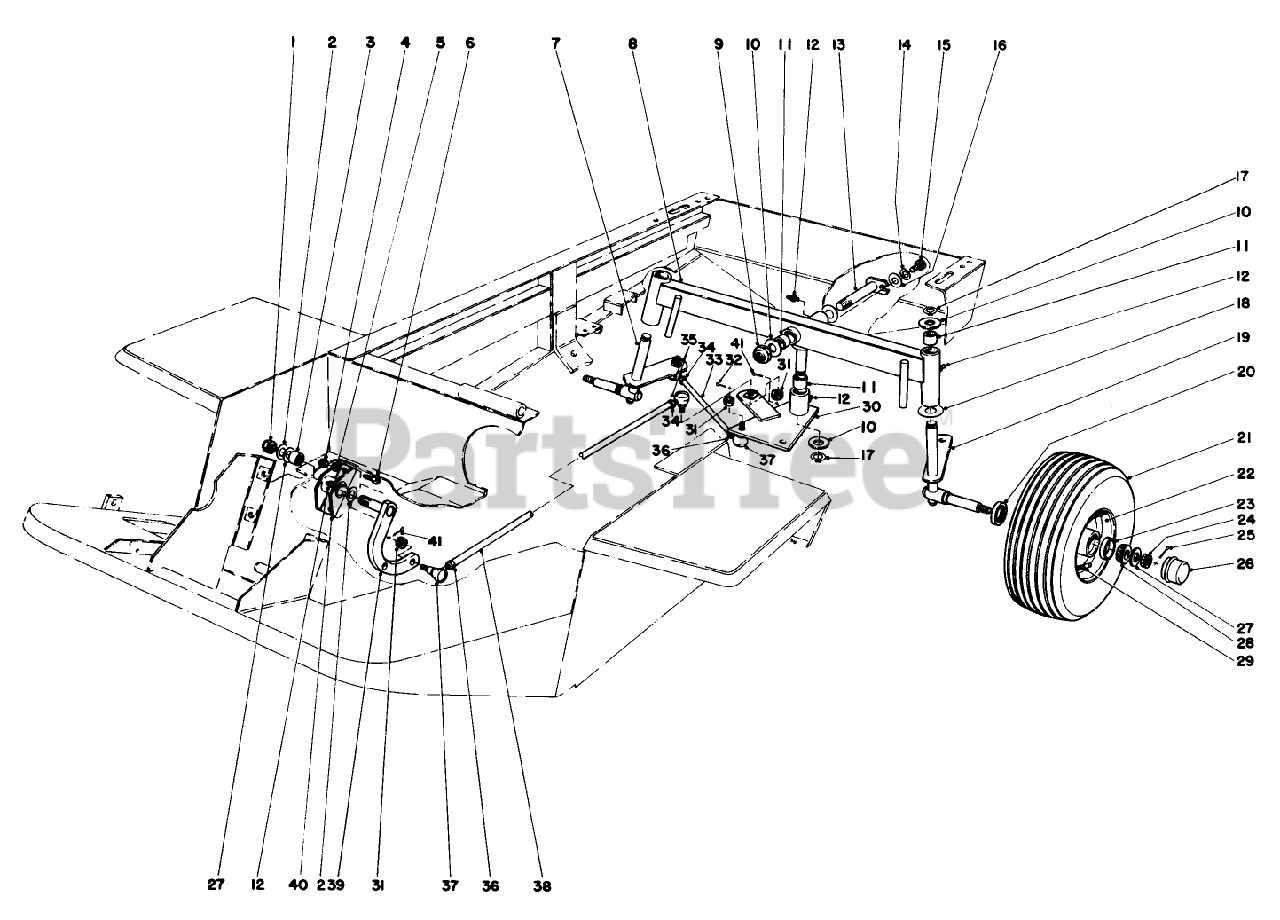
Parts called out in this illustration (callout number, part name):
1	NUT-LOCK, NI
2	THRUST WASHER
3	BEARING-NEEDLE
4	NUT-HEX
5	WASHER-LOCK
6	SCREW-HH
7	Spindle R.H.
8	Axle (Incl. Ref.#11 & 12)
9	NUT-LOCK, NI
10	WASHER-THRUST
11	BUSHING
12	FITTING-GREASE
13	Pin-RearAxle
14	WASHER-LOCK
15	SCREW-HH
16	WASHER-FLAT
17	RING-RETAINING
18	WASHER-THRUST
19	Spindle L.H.
21	TIRE 4 PLY
22	Wheel (Incl.Ref.#23)
23	Bearing Cup
24	NUT-HEX, SLOTTED
25	PIN-COTTER
26	CAP-DUST
27	WASHER-FLAT
28	BEARING-CONE, TAPERED
29	VALVE STEM AND CAP ASM
30	Steering Plate (Incl.Ref.#11 & 12
31	NUT-SLOTTED
32	PIN-COTTER
33	STRG TIE ROD R
34	NUT-HJ (LH THREAD)
35	Socket Assembly L.H. (Incl.Ref.#31)
36	NUT-JAM
37	Socket Assembly R.H. (Incl.Ref.#31)
38	REAR STRG TUBE PP
39	PIVOT ARM WA
40	Pivot Mount (Incl.Ref.#3 & 12)
41	PIN-COTTER
